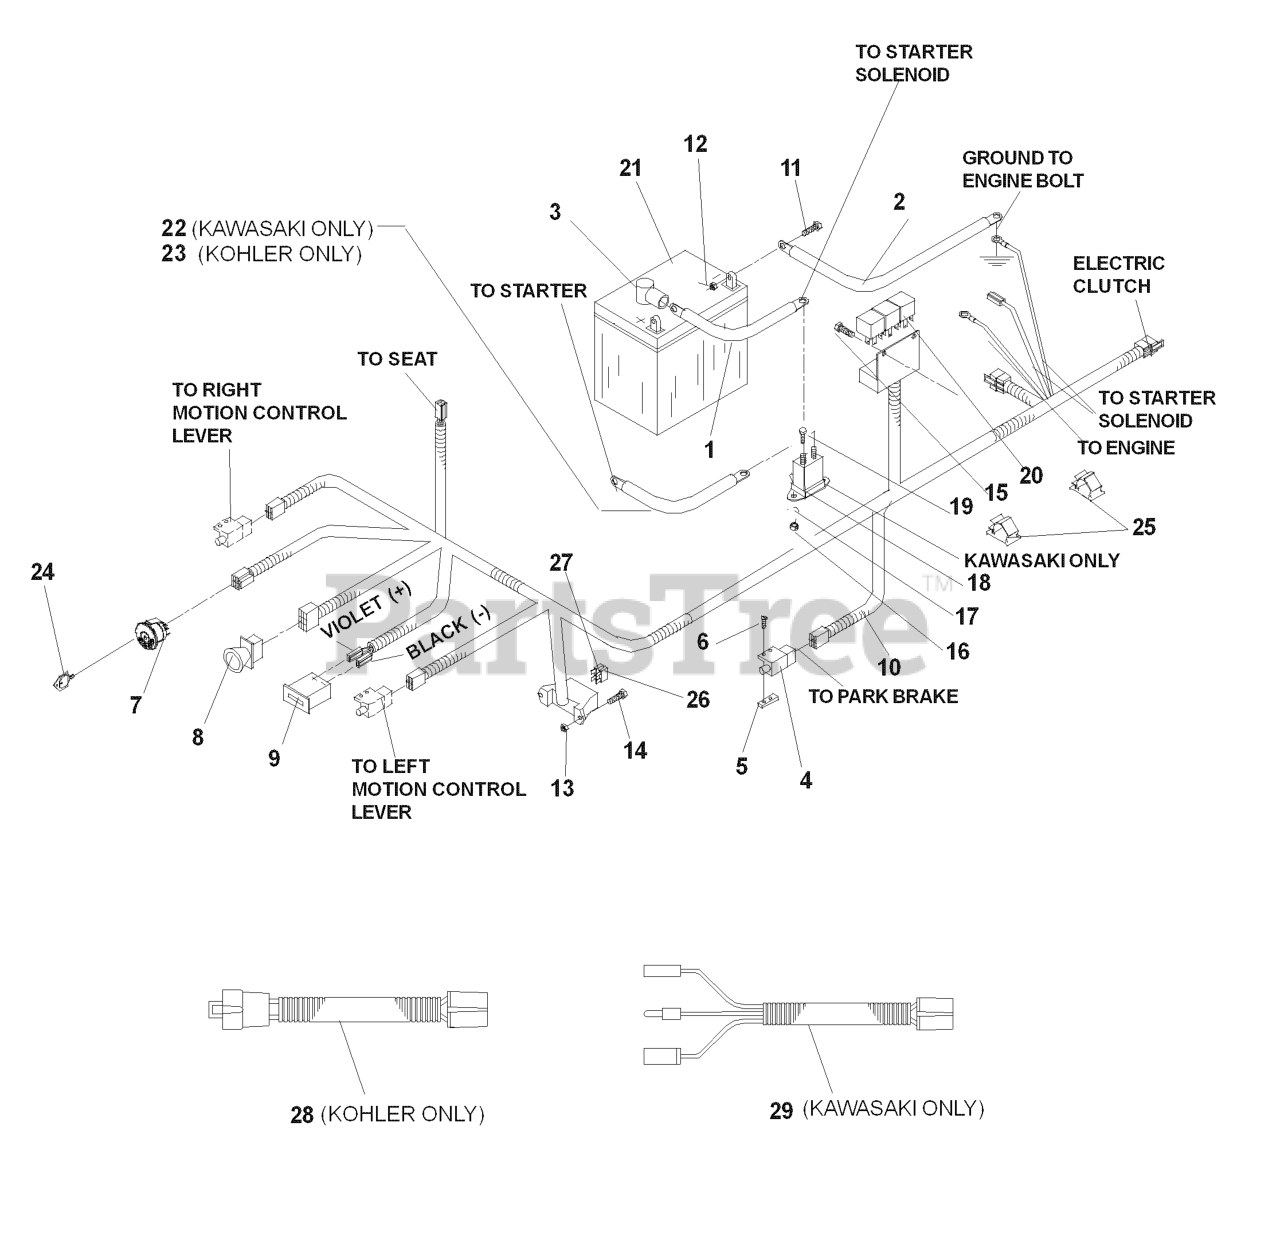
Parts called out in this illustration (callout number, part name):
1	CABLE POSITIVE, LONG
2	CABLE-NEGATIVE
4	SWITCH, INTERLOCK
5	TAPPED PLATE
6	SCREW #10-24 X 5/8
7	RP IGNITION SWITCH
8	RP.SWITCH, BLADE
9	HOUR METER
10	FRAME HARNESS
11	HCS 5/16C X 3/4
12	NUT 5/16 NYLOC
13	NUT 10-24 NYLOC
14	SCREW, #1--24 X 1/2 SLOTTED
15	SCREW #10 X 1/2 SELF TAPPING
16	NUT 1/4C CENTERLOCK
17	WASHER 1/4 INT TOOTH
19	HCS 1/4C X 5/8
21	BATTERY, 12 V 330 AMP
22	POST.CABLE LONG
23	CABLE POSITIVE
24	KEY
25	PUSH-MOUNT WIRE CLIP
26	FUSE, 7.5 AMP 32 VOLT ATO
27	FUSE, 20 AMP 32 VOLT ATO
28	KOH PIGTAIL
29	KAW PIGTAIL
